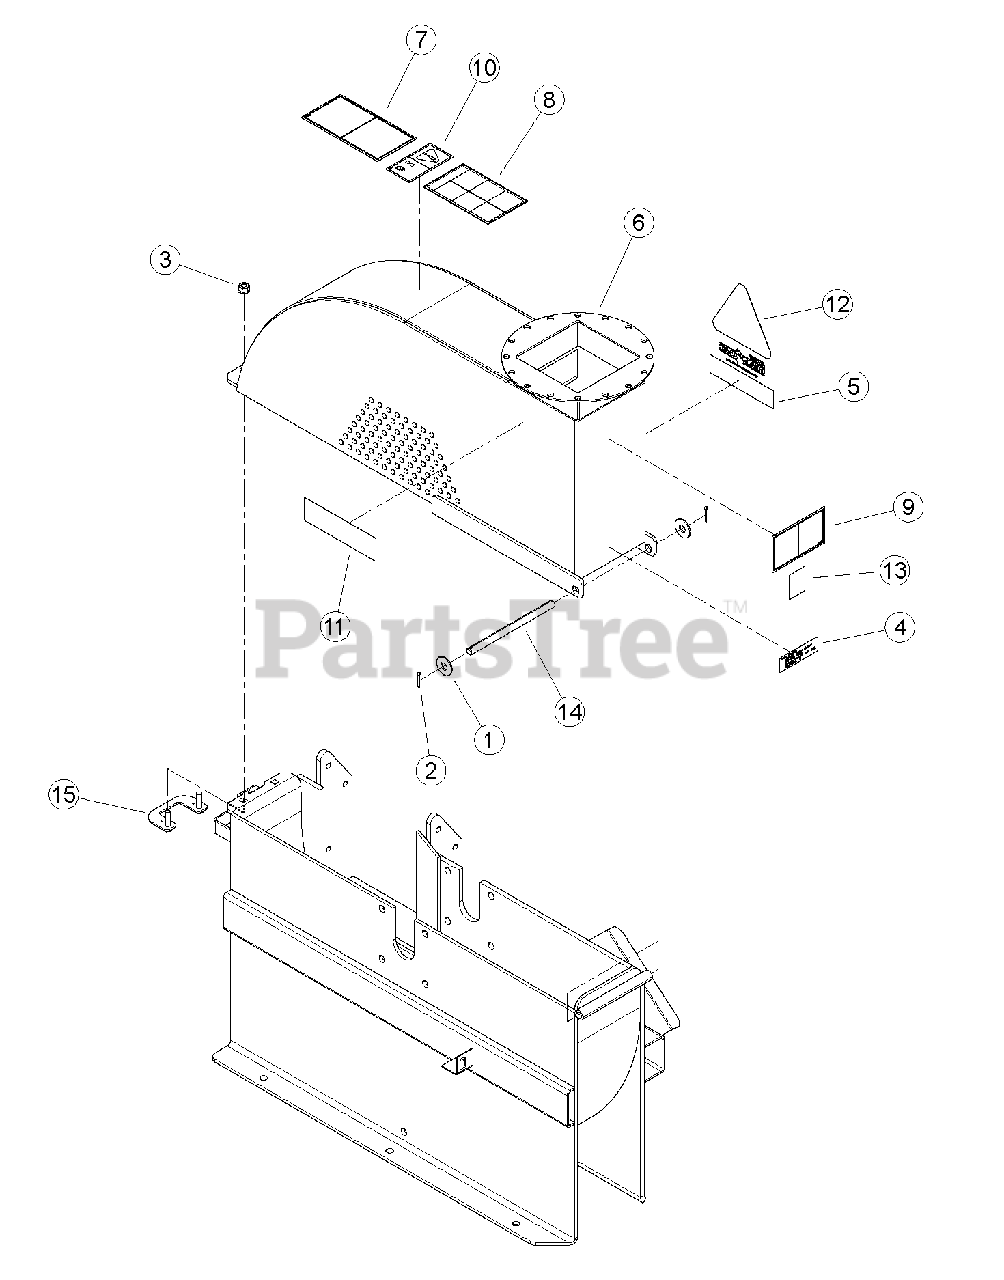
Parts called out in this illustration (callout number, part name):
1	WASHER, 1/2" FLAT ZP
2	PIN, 1/8 X 1.00 ZP COTTER
3	NUT, 3/8-16 NYLOCK FLANGE
4	DECAL, ATLANTIC BRIDGE LTD INFO (CE COMPLIANT ONLY)
5	DECAL, MODEL CH911DH
6	ASSEMBLY, CHIPPER COVER W/ DECALS
7	DECAL, KNIFE ACCESS ISO
8	DECAL, OPERATING INSTRUCTIONS ISO
9	DECAL, DISCHARGE ISO
10	DECAL, MAINTENANCE ISO
11	DECAL, ECHO BEARCAT 6.82 X 1.90
12	DECAL, CHIP IT
13	DECAL, ECHO BEARCAT QR CODE
14	SHAFT CHIPPER TOP PIVOT
15	WELDMENT, CHIPPER HOUSING ACCESS
